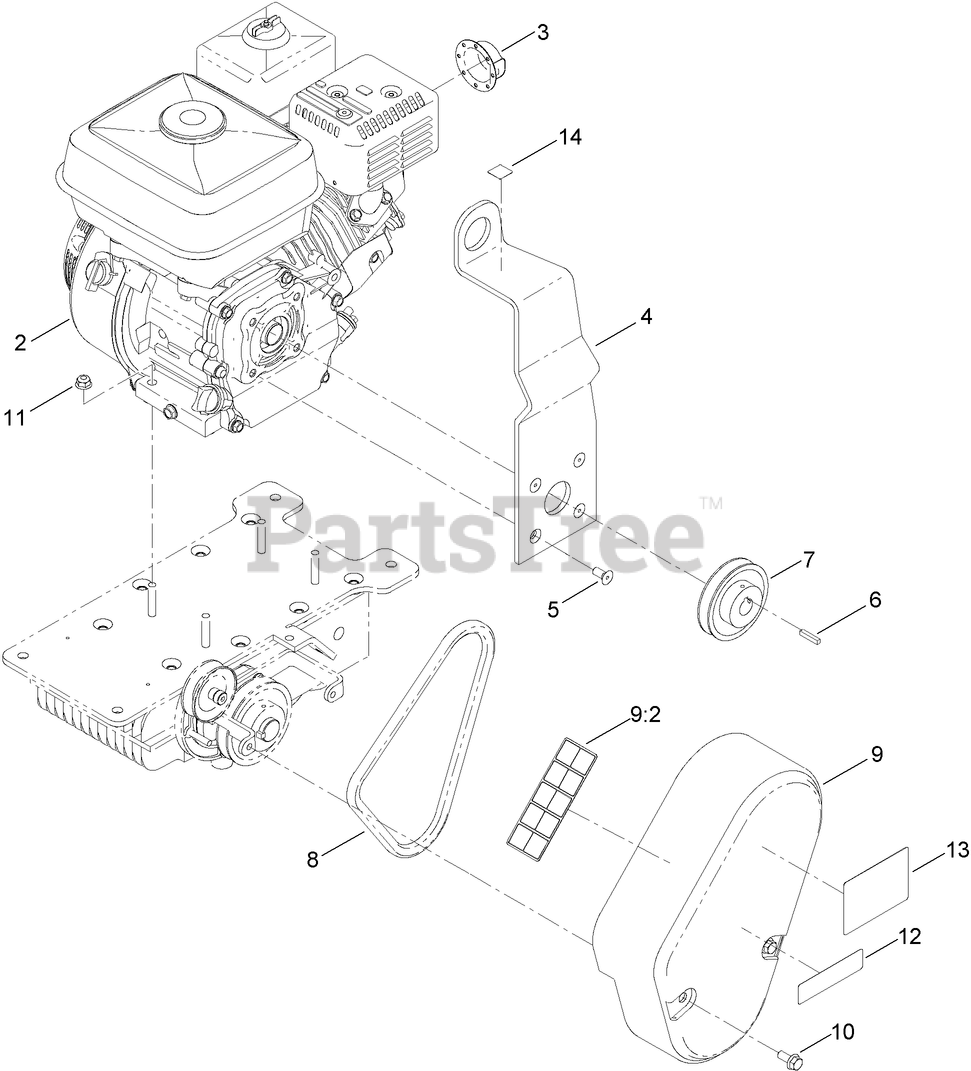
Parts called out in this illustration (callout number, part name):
2	ENGINE-HONDA, GX160
3	DEFLECTOR-EXHAUST
4	PLATE-EYE, LIFT
5	SCREW
6	KEY-SQUARE
7	SHEAVE
8	BELT-V
9	BELT GUARD ASM
9:2	DECAL-WARNING, POWER TROWEL
10	SCREW-HHF
11	NUT-HF, NI
14	DECAL-POINT, LIFT
